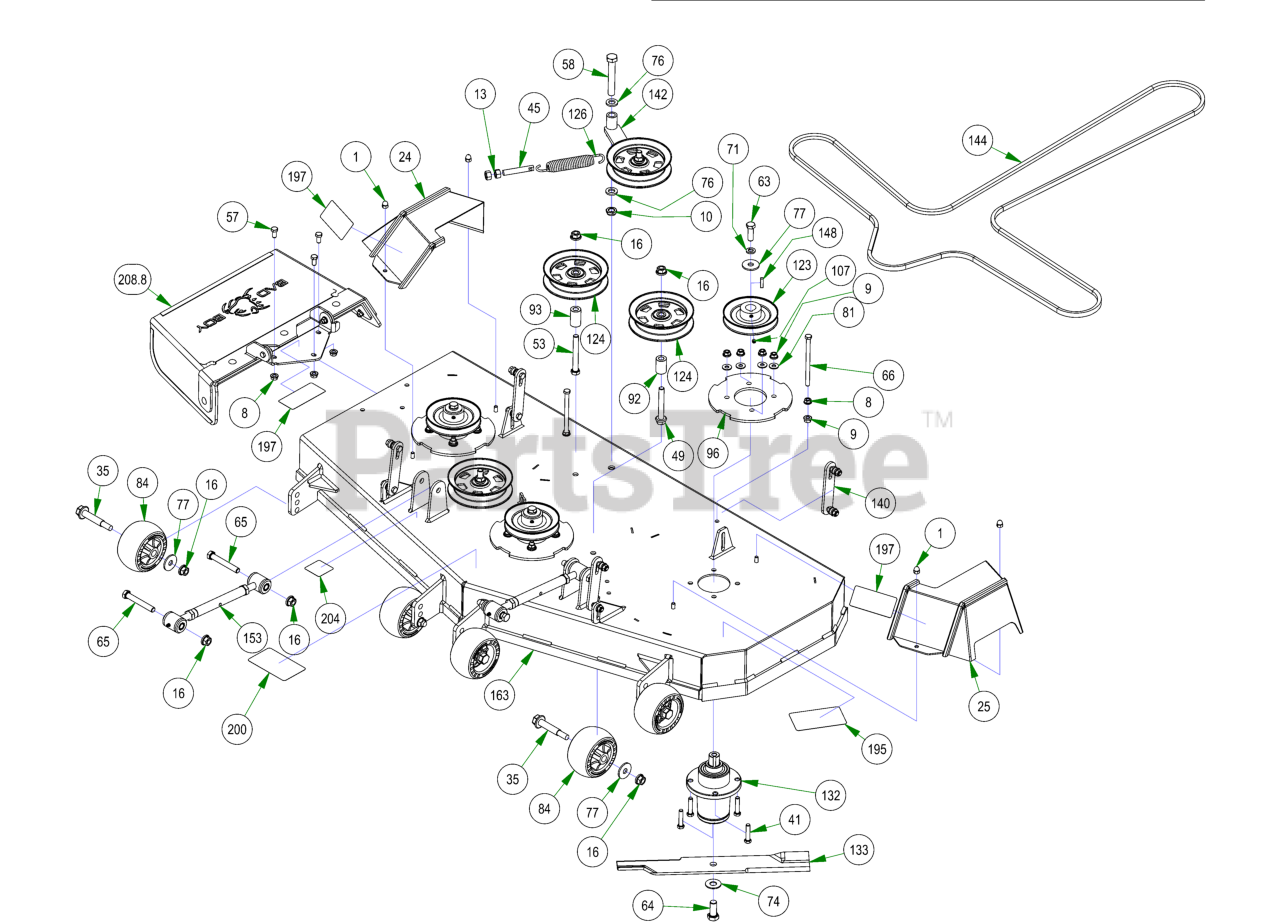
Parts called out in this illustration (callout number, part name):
1	5/16-18 ACORN NUT HIGH-CROWN ZC
8	3/8-16 HEX SERRATED FLANGE NUT HARD/ZINC
9	3/8-16 NYLON INSERT FLANGE LOCKNUT (GR.F) ZINC
10	5/8-11 NYLON INSERT JAM LOCKNUT ZINC
13	1/2-13 HEX NUT ZINC
16	1/2-13 NYLON INSERT FLANGE LOCKNUT ZINC
24	2021 Maverick 54”/60” RH Pulley Cover
25	2021 Maverick 54”/60” LH Pulley Cover
35	Deck Wheel Bolt
41	3/8-16 X 1-3/4 HEX C/S (GR.5) ZC
45	All Thread
49	1/2-13 X 3-1/2 HEX FLANGE BOLT (GR.8) ZINC
53	1/2-13 X 4 HEX CAP SCREW (GR.8) ZINC YELLOW
57	3/8-16 X 3/4 HEX CAP SCREW (GR.5) ZINC
58	5/8-11 X 4 HEX CAP SCREW (GR.8) ZINC YELLOW
63	1/2-20 X 1-1/2 HEX CAP SCREW (GR.5) ZINC
64	5/8-18 X 1-1/2 HEX CAP SCREW (GR.8) ZINC YELLOW
65	1/2-13 X 3-1/2 HEX CAP SCREW (GR.5) ZINC
66	3/8-16 X 5-1/2 HEX CAP SCREW (GR.5) ZINC
71	1/2 SPLIT LOCKWASHER (GR.8) ZINC/YELLOW
74	5/8 USS FLAT WASHER (1-3/4" OD) GR.8 ZINC YELLOW
76	.635 ID X 1.120 OD X .140 THICK FLAT WASHER NYLON
77	1/2 BELLEVILLE WASHER (1-5/8 OD X .140 THK) ZINC
81	5/16 USS FLAT WASHER (7/8 OD) ZINC
84	Deck Wheel
92	.502 ID X .750 OD X 1.500 Long Spacer
93	1 3/4" Pulley Spacer
96	Deck Spindle Support Plate
107	5/16-24 X 1/4 SOCKET SET SCREW (CUP PT) PLAIN
123	5.25" Deck Spindle Pulley
124	5-3/4 Idler Pulley
126	Deck Idler Spring
132	Spindle Assembly
133	54" Fusion Blade for ZT/Mav/Outlaw/Revolt
140	Deck Hanger Assembly
142	2017 MZ/ZT Deck Idler Assembly
144	B155.75 Deck Belt
148	1/4 X 1 SQ MACHINERY KEY 1018 STL PLN
153	2018 Maverick Turnbuckle (Top Link)
163	2023 54" x 5" Deck
195	2018 54" Deck Decal
197	Danger Decal-Spindle/Discharge
200	Deck Belt Route Decal
204	Deck Impact Patent Decal 9591803
208	Discharge Chute Assembly
